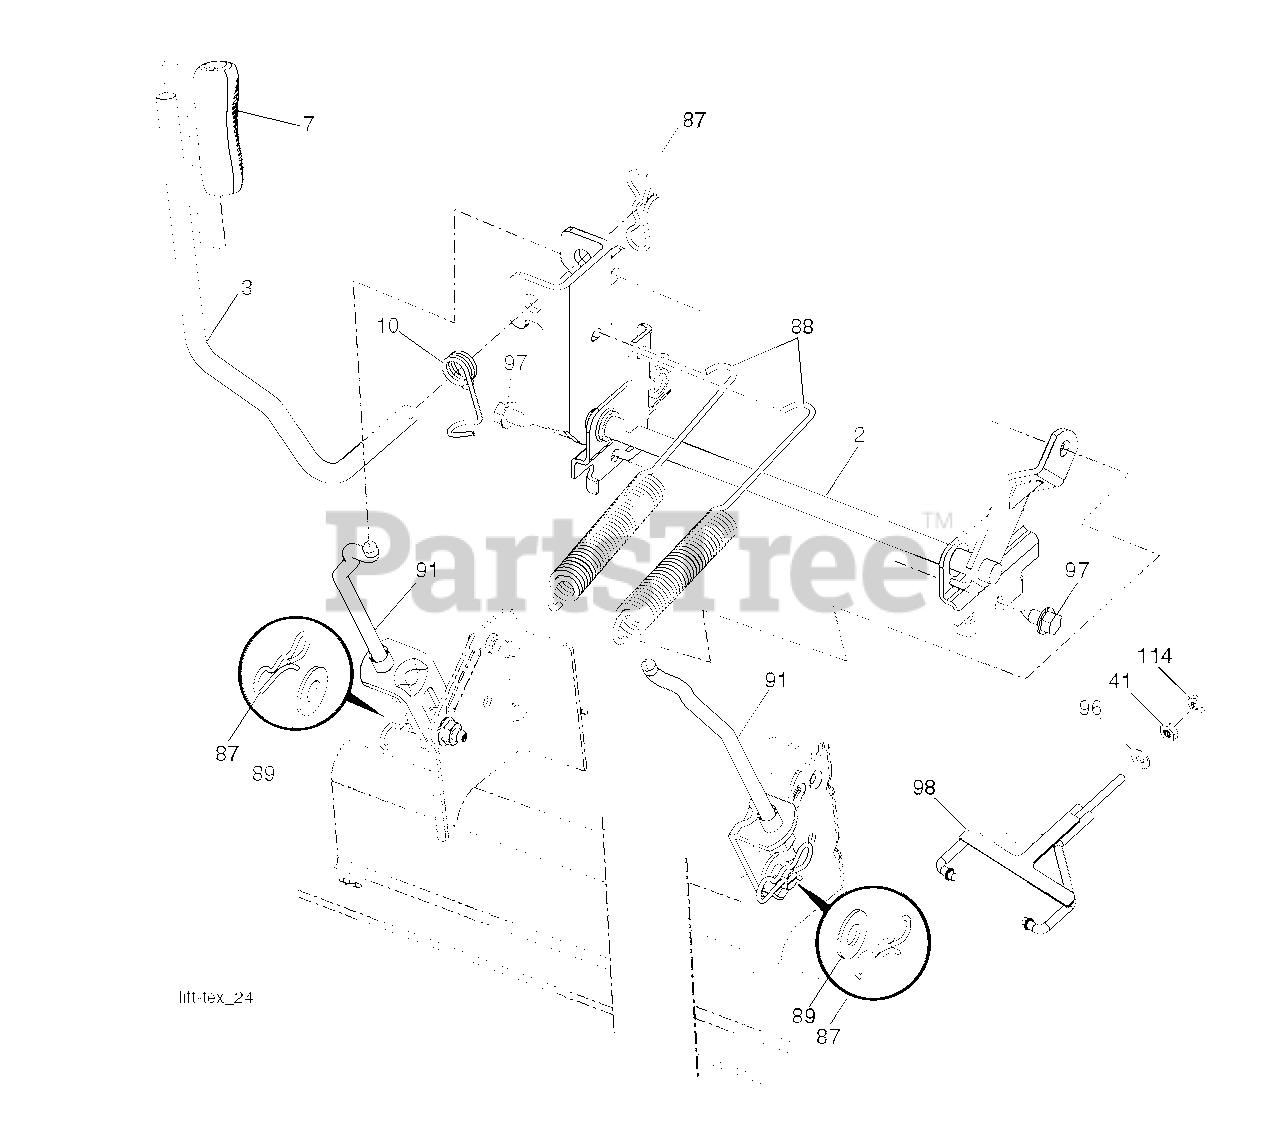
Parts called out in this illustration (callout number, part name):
2	SHAFT.ASM.CROSS.LIFT
3	LEVER.LIFT.HANDLE.GT
7	GRIP.HANDLE.LIFT.PVC.BLACK
10	SPRING.TORSION.LIFT.HANDLE
41	NUT, LIFT LINK 7/16-20
87	PIN.COTTER.7/16.BOW TI.
88	SPRING.LIFT.ASSIST.GT2
89	WASHER.CLEAR.ZINC
91	LINK.ASM.LIFT.54"TG
96	BUSHING SPHERICAL SUSP. FRONT
97	SCREW, 3/8-16X3/4
98	SUSPENSION WLDT FRONT DECK
114	NUT **
